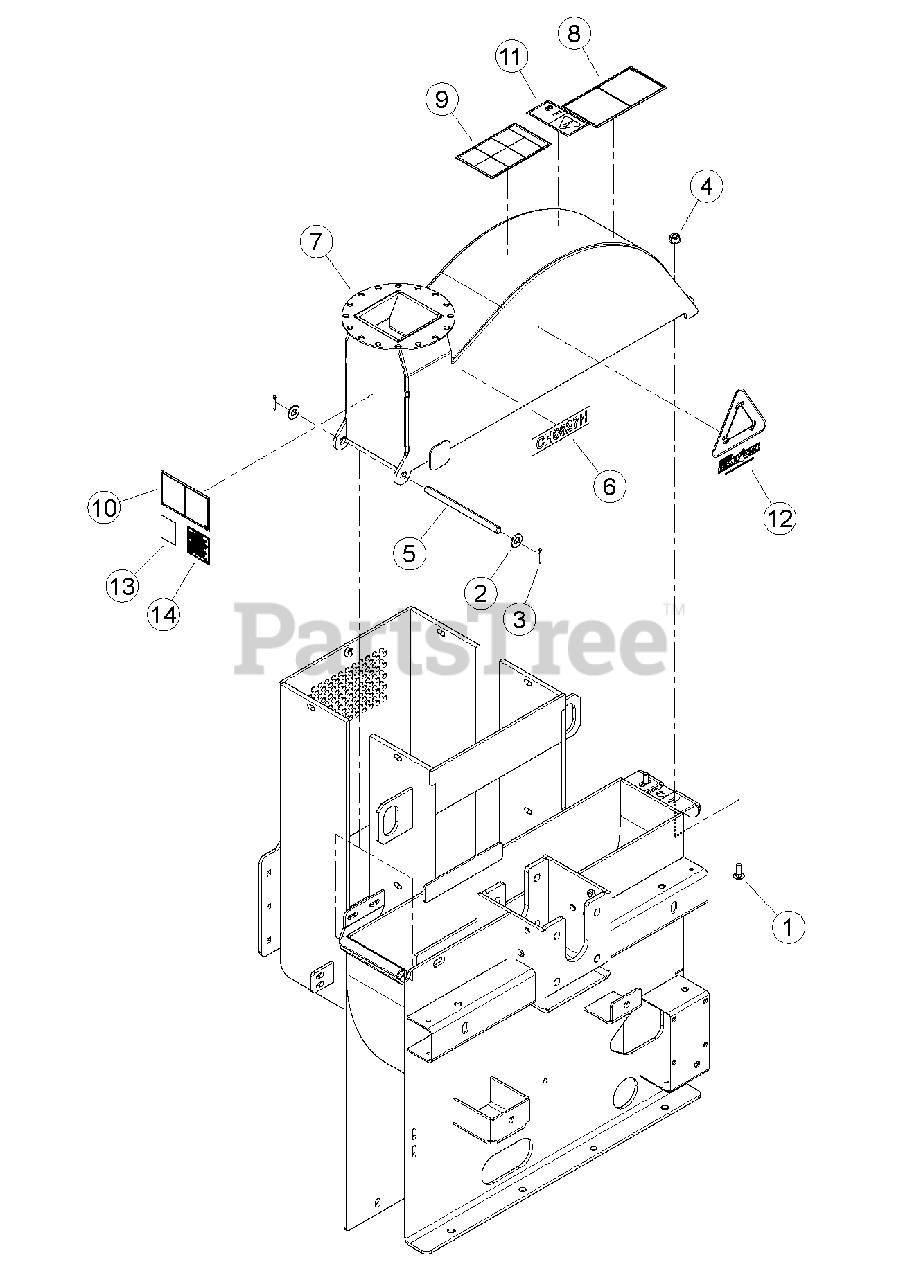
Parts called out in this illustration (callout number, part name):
1	BOLT, 3/8-16 X 1 GR5 CRG
2	WASHER, 1/2 SAE FLAT
3	PIN, 1/8 X 1.00 ZP COTTER
4	NUT, 3/8-16 NYLOCK FLANGE
5	SHAFT, CHIPPER TOP PIVOT
6	DECAL, MODEL CH6627H
7	ASSEMBLY, CHIPPER COVER W/ DECALS
8	DECAL, KNIFE ACCESS ISO
9	DECAL, OPERATING INSTRUCTIONS ISO
10	DECAL, DISCHARGE ISO
11	DECAL, MAINTENANCE ISO
12	DECAL, CHIP IT
13	DECAL, ECHO BEARCAT QR CODE
14	DECAL, SPARK ARRESTOR
